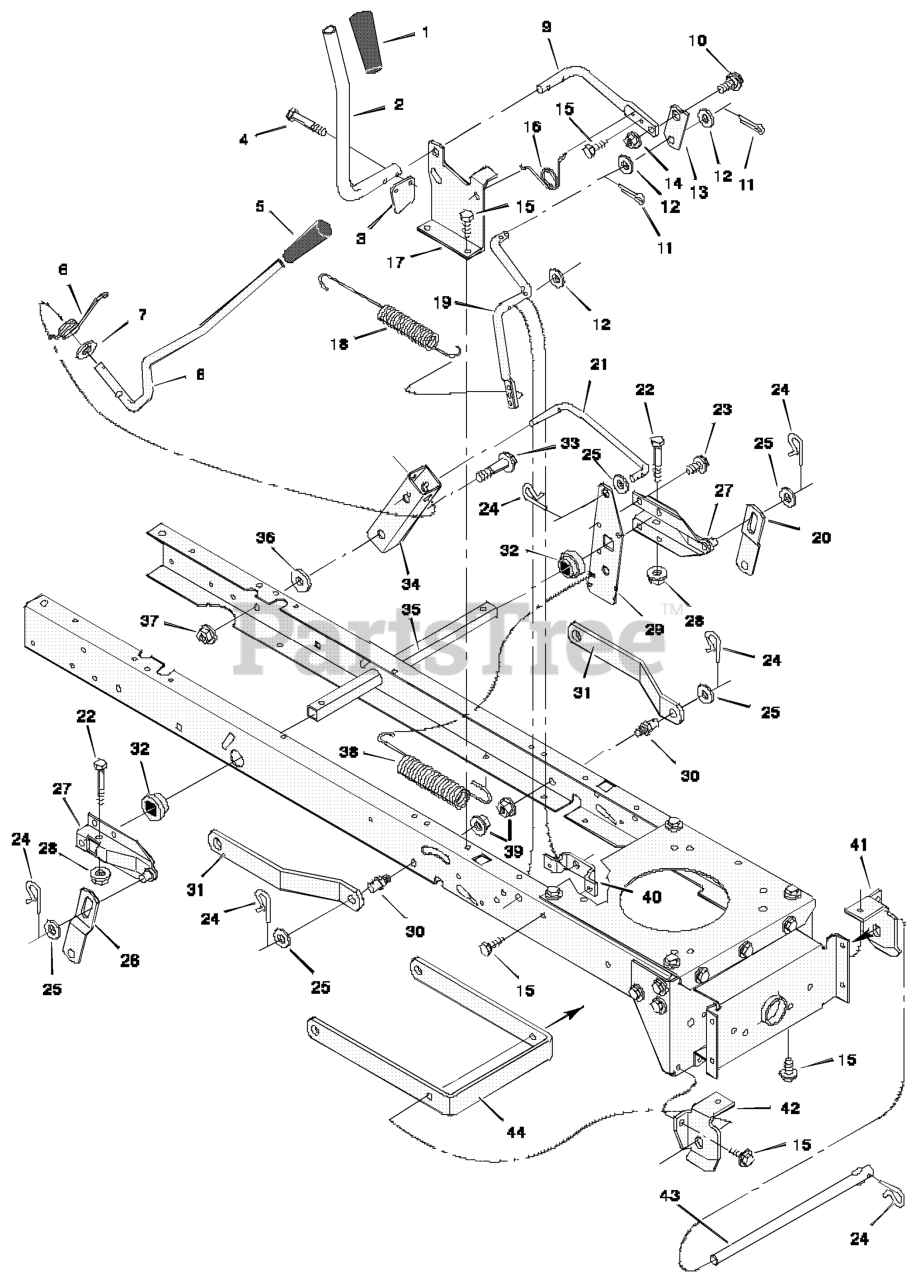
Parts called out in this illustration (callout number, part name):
1	Grip
3	Pad, Switch
4	Screw, Hex
5	Grip
8	Lever, Lift
9	Lever, PTO
10	Bolt, Shoulder
11	Pin, Cotter
12	Washer
13	Link, PTO
14	Nut, Flange
17	Bracket, PTO
19	Crank, PTO
20	Link, Left Lift
21	Link, Lift
24	Pin, Hair
26	Link, Right Lift
27	Lever Assembly, Lift
28	Nut, Flange
29	Plate, Lift Arm
30	Pin
31	Bracket, Rear Suspension
32	Bushing
33	Bolt, Shoulder
34	Bracket, Pivot
35	Tube, Deck Lift
37	Nut, Flange
39	Nut, Flange
40	Bracket, PTO
41	Hanger, Left Deck
42	Hanger, Right Deck
43	Rod, Hanger
44	Bracket, Suspension
